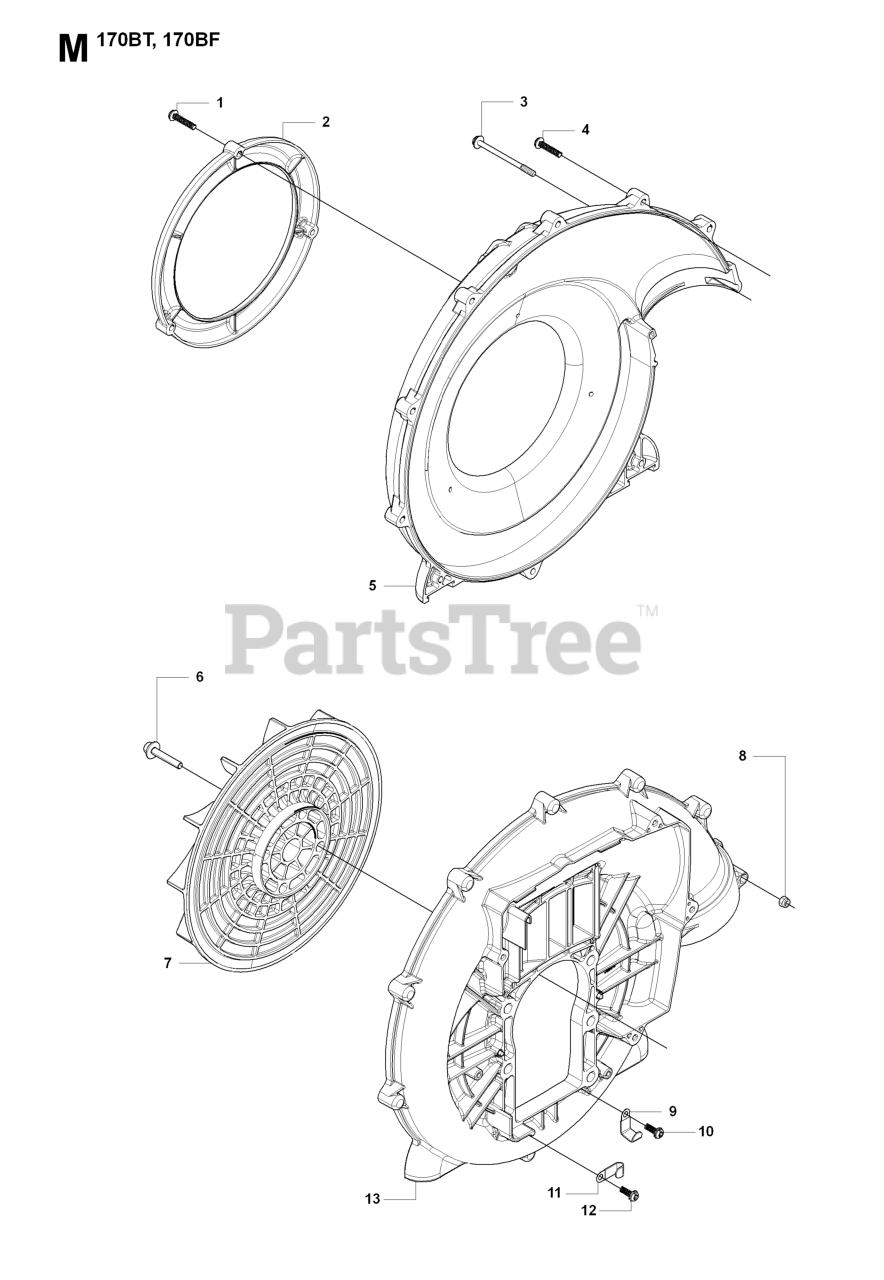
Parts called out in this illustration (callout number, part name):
5	VOLUTE COVER
11	CLAMP
13	VOLUTE CASE
